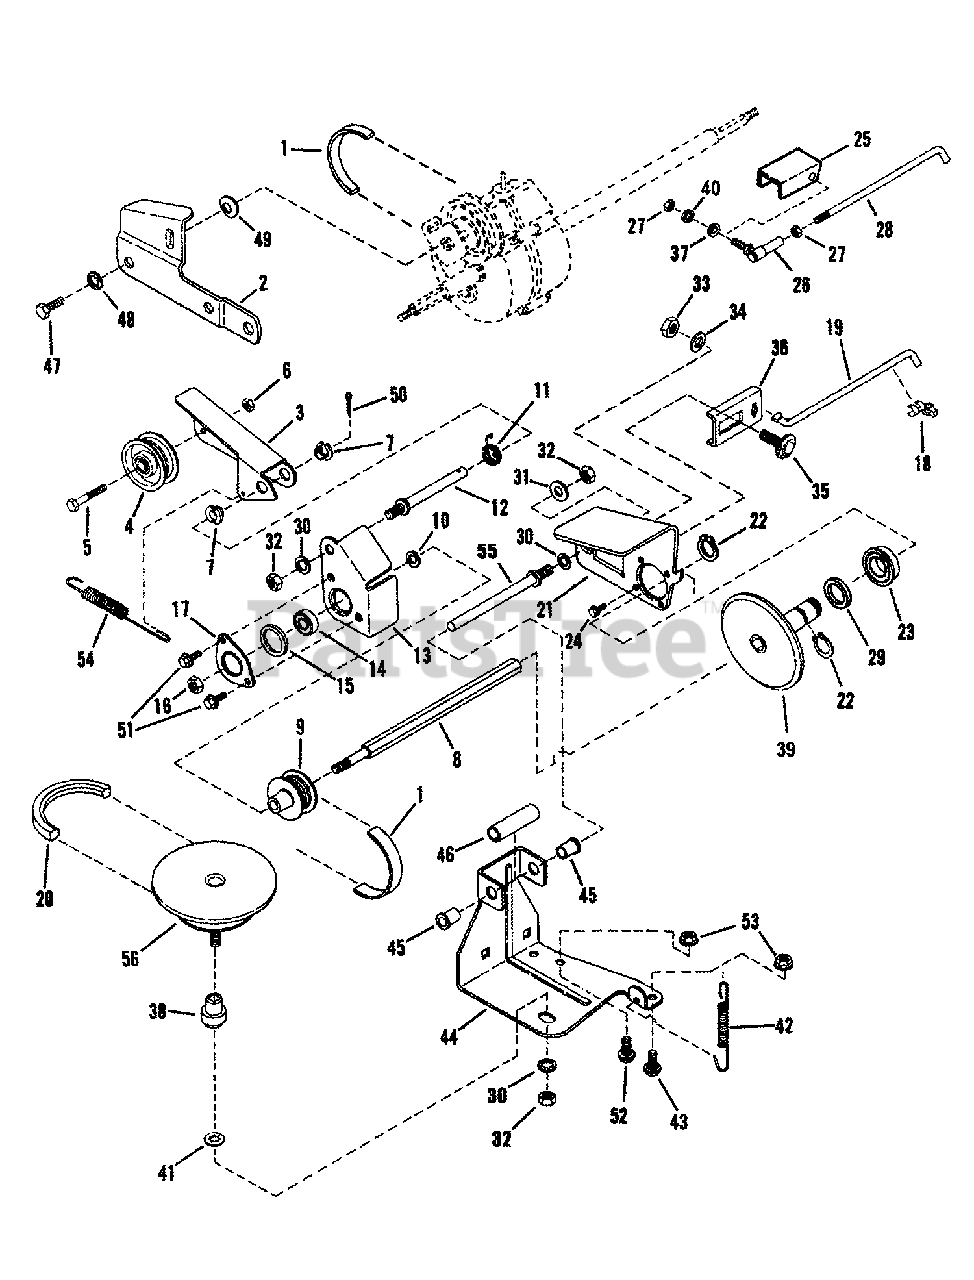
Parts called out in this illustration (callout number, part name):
1	BELT, Poly-Vee
2	LINK, Differential
3	ARM, Clutch Idler
4	PULLEY, Idler
5	SCREW, 1/4-28 x 1-3/8" Hex Head Cap GR5
6	NUT, 1/4-28 Hex Top Lock
7	BUSHING, 3/8" Plastic
8	SHAFT, Hex Drive
9	PULLEY, Poly-V, 2" O.D.
10	WASHER, 3/8" Flat
11	SPRING, Torsion
12	STUD, Idler (3/8-24 thread)
13	HOLDER, Bearing (Inner Half)
14	BEARING, Ball, .38 I.D. Spherical O.D.
15	O-RING
16	NUT, 3/8-24 Hex Center Lock GR5 or B
17	HOLDER, Bearing (Outer Half)
18	CLIP, 1/4" Right Arc (Transfer Rod)
19	ROD, Transfer
20	BELT, Engine Drive 3L (Stretch)
21	PLATE, Thrust
22	RING, 5/8" External Retaining
23	BALL BEARING, 3/4" I.D.
24	SCREW, #10-32 x 1/4" Self-Tap Machine
25	SHIELD, Hex Shaft
26	BALL JOINT, 1/4-28
27	NUT, 1/4-28 Hex GR5
28	LINK, Transfer
29	WASHER, 3/4" Shim
30	WASHER, 3/8" Internal Tooth Lock
31	WASHER, 3/8" Flat
32	NUT, 3/8-24 Hex, GR B
33	NUT, 5/16-18 Hex GR5 or B
34	WASHER, 5/16" Split Lock
35	BOLT, 5/16-18 x 3/4" Short Neck Carriage GR5
36	CONNECTOR, Transfer Rod
37	WASHER, Flat 1/4"
38	BUSHING
39	DISC, Driven (Cantilever)
40	WASHER, 1/4" Internal Tooth Lock
41	RETAINER, 3/8" Bolt
42	SPRING, Wheel Drive
43	BOLT, 5/16-18 x 5/8" Short Neck Carriage GR5
44	ASSEMBLY, Deck Bracket (Incl. items 44, 45 & 46)
44	BRACKET, Deck
44	BRACKET, Deck (Incl. item 7)
45	BUSHING, lange Plastic
46	SPACER
47	SCREW, 5/16-18 x 1/2" Hex Head Cap, GR5
48	WASHER, 5/16" Internal Tooth Lock
49	WASHER, Spring
50	PIN, 3/32 x 1/2" Cotter
51	SCREW, 1/4-20 x 1/2" Hex Washer Self-Tap
52	BOLT, 5/16-18 x 1/2" Short Neck Carriage GR5
53	NUT, 5/16-18 Hex Flange Lock, GR5
54	SPRING, Clutch
55	GUIDE, Thrust Plate (3/8-24 thread)
56	KIT, Drive Disc Assembly
